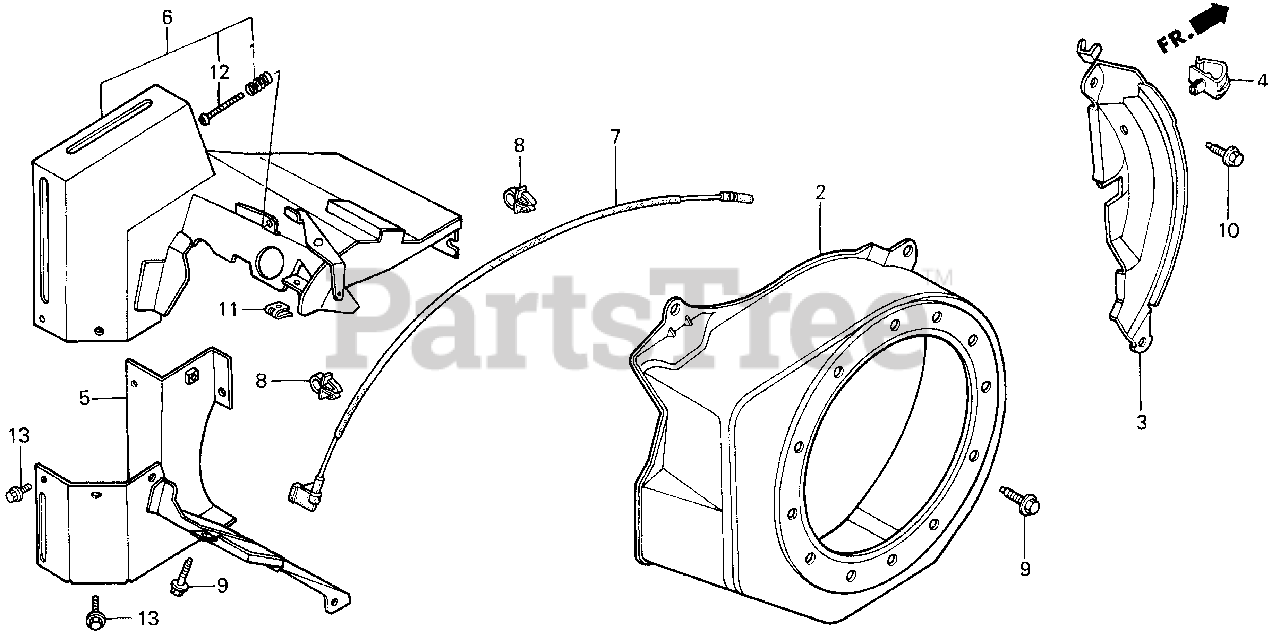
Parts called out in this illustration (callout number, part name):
1	SPRING, CONTROL ADJUSTING
2	COVER, FAN
3	PLATE, SIDE (ALERT & LAMP)
4	CLAMP, CORD
5	SHROUD (LOWER)
6	SHROUD ASSY. (UPPER)
7	WIRE, STOP SWITCH
7	WIRE, STOP SWITCH (NOT AVAILABLE)
8	HOLDER, STOP SWITCH WIRE
9	BOLT, FLANGE (6X12) (CT200)
10	BOLT, FLANGE (6X20) (CT200)
11	NUT, SPRING (5MM)
12	SCREW, PAN (5X32)
13	BOLT, FLANGE (6X10)
